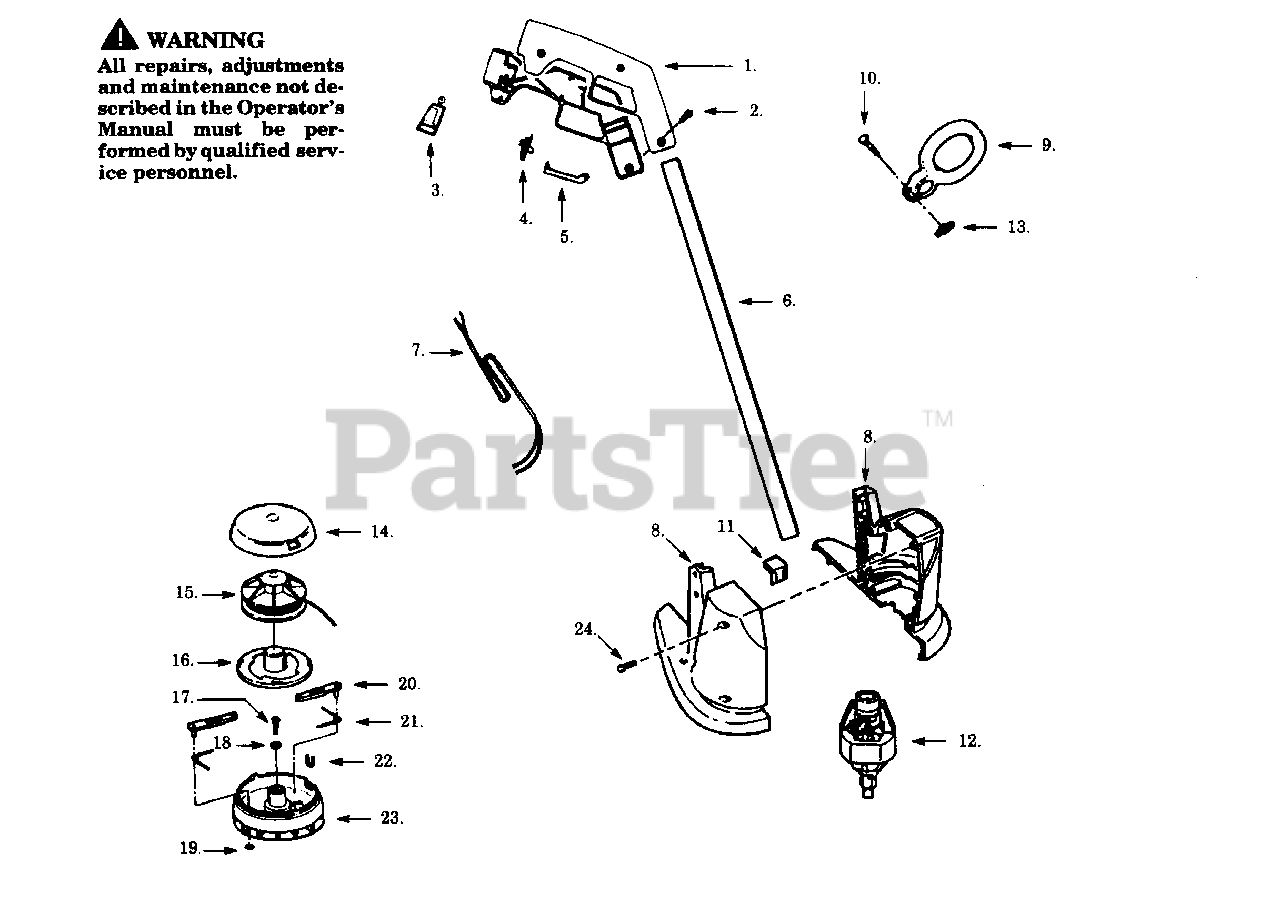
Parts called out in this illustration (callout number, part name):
1	Handle Set
3	Cord Retainer
4	On/Off Switch
5	Trigger Switch
6	Tube Ass'y.
7	Plug/Harness Ass'y.
8	Housing Set
9	Assist Handle
11	Blade/Bracket Ass'y.
12	Motor Ass'y.
13	Wing Nut
15	Spool w/Line
19	Push Nut
22	Line Shield
23	Housing Ass'y.
